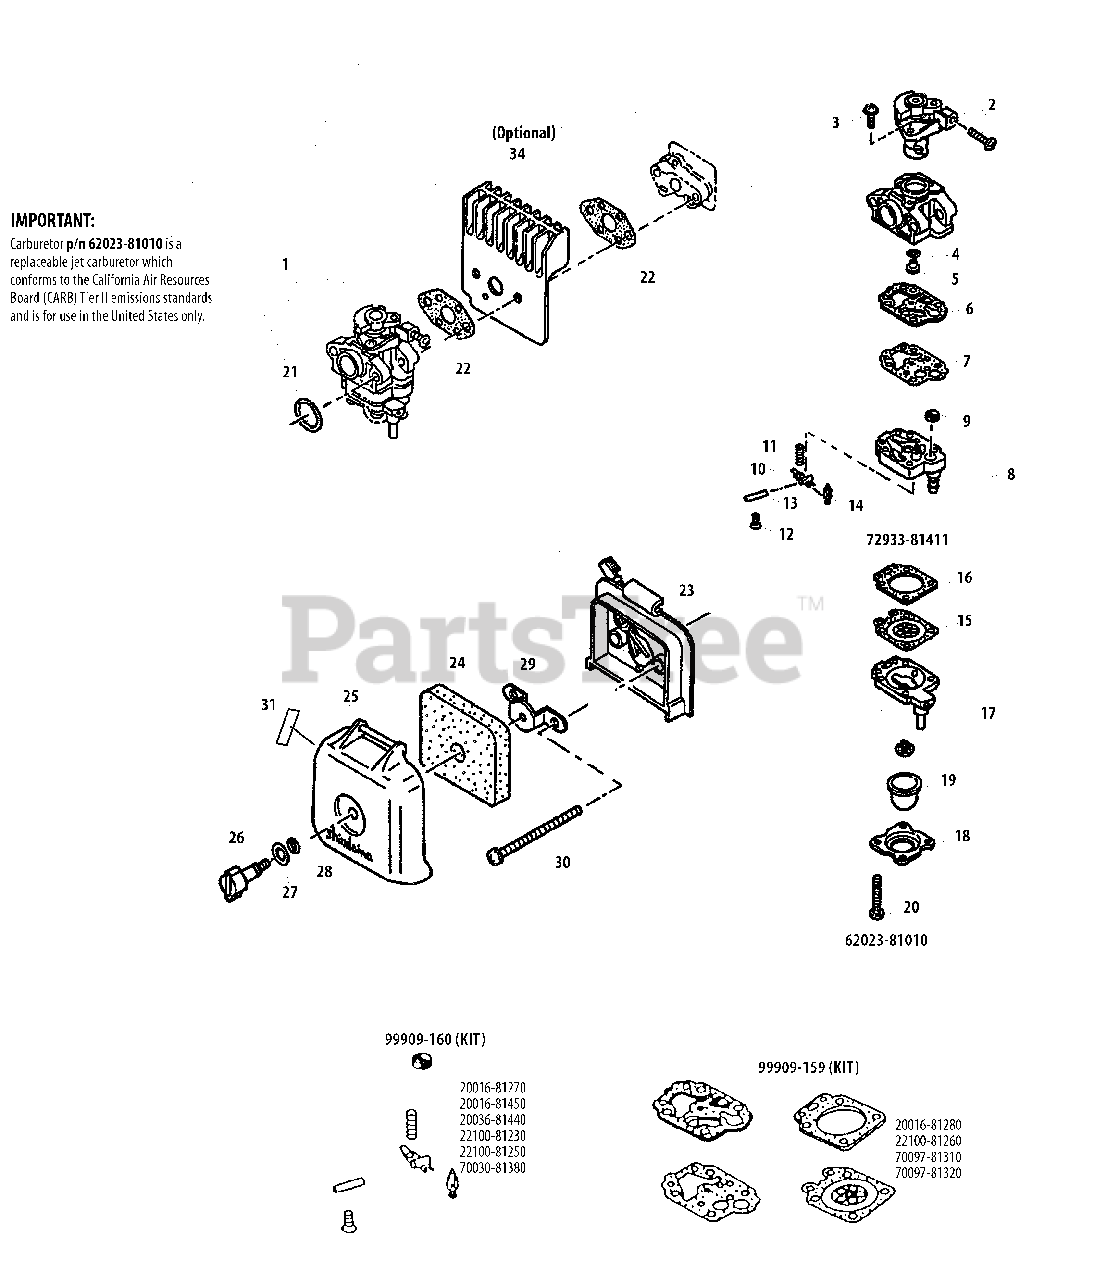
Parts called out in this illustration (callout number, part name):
1	CARBURETOR
2	VALVE ASSY, THROTTLE
3	SCREW, THROTTLE COLLAR
4	O-RING
5	JET, MAIN
6	GASKET, PUMP
7	DIAPHRAGM, PUMP
8	BODY ASSY, PUMP
9	SCREEN, FUEL INLET
10	VALVE, INLET NEEDLE
11	SPRING, METERING LEVER
12	SCREW
13	PIN, METERING LEVER
14	LEVER, METERING
15	DIAPHRAGM, METERING
16	GASKET, METERING DIAPHRAGM
17	BODY ASSY, PURGE
18	RETAINER, PURGE BULB
19	BULB, PURGE
20	SCREW
21	O-RING 15
22	GASKET, CARBURETOR
23	CASE, AIR FILTER
24	FILTER, AIR
25	COVER, AIR FILTER
26	THUMBSCREW
27	O-RING
28	WASHER, CONE M6
29	BRACKET
30	SCREW - 5×67
31	LABEL, CHOKE
34	DEFLECTOR, HEAT
99909-159	GASKET / DIAPHRAGM KIT
99909-160	VALVE KIT, INLET NEEDLE
